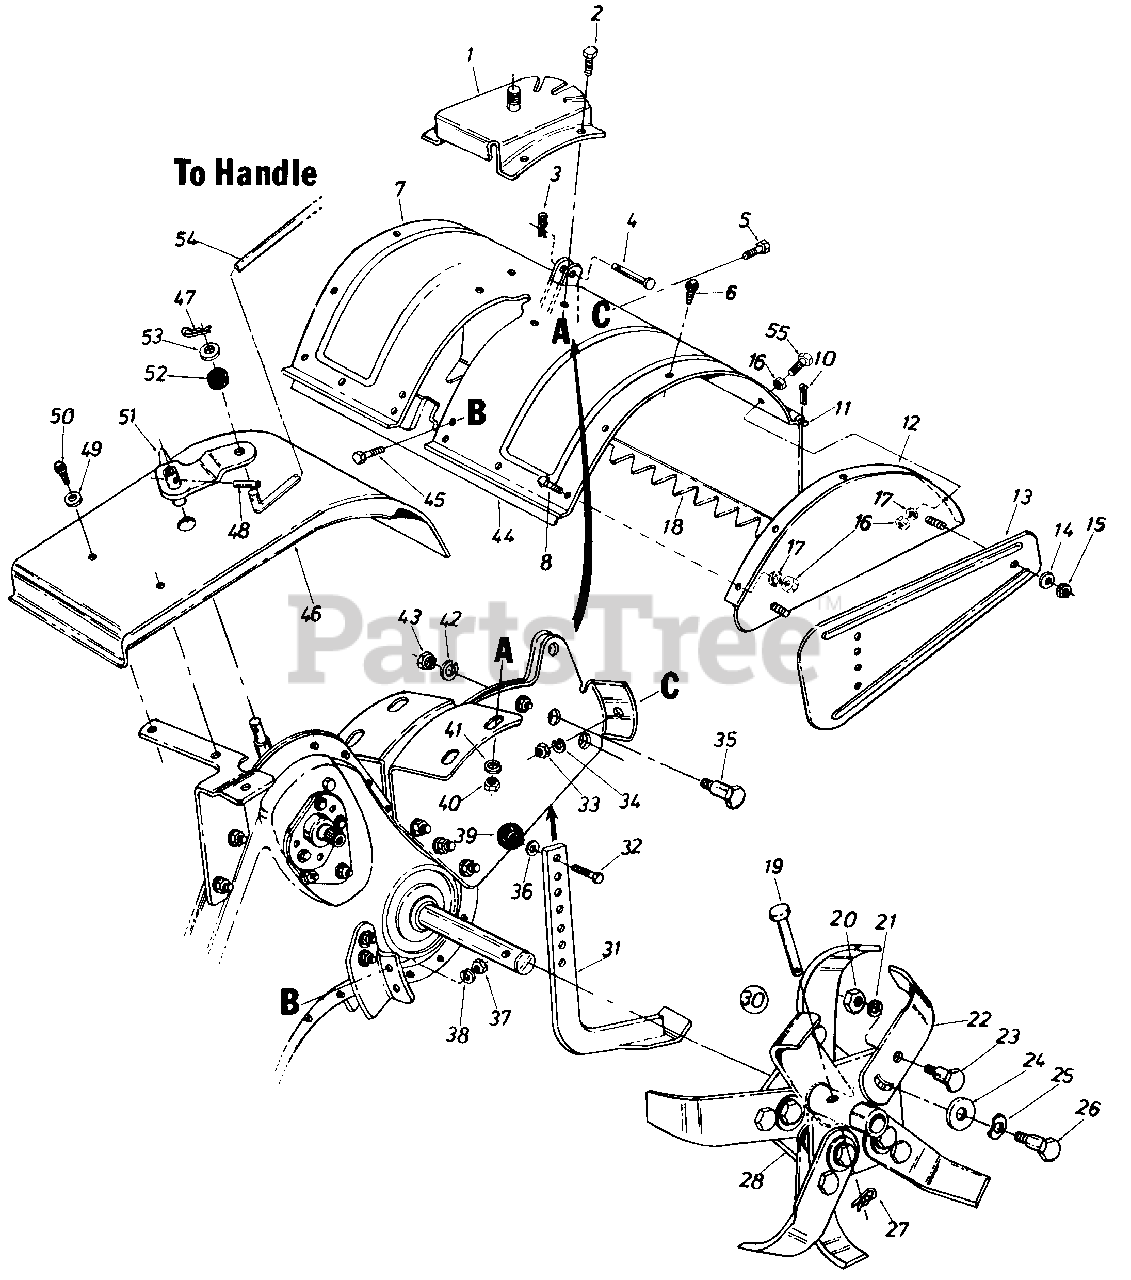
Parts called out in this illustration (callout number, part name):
3	Intern. Cotter Pin 5/16" Dia.
4	Clevis Pin .375" Dia.
5	Hex Bolt 5/16-18 x .75" Lg.
6	Hex Wash. Tap Scr.
8	Bracket Reinforcement-18"
10	Cotter Pin 3132" Dia. x .75"*
11	Tiller Flap Rod
12	End Cover Ass'y.
15	Hex Nut 5/16-18 Thd.*
16	Hex Nut 5/16-18 Thd.
17	L-Wash. 5/16" I.D.*
19	Clevis Pin .375" Dia.
20	Hex Nut 3/8-24 Thd.*
21	L-Wash. 3/8" I.D.-H.D.
22	13" Dia. Articulating Tine
23	Shld. Bolt 1/2" Dia. x .175
24	Fl-Wash. .51" I.D. x 1.50"
25	Bell-Wash. .515" I.D. x 1.14"
26	Shld. Bolt 1/2" Dia. x .320
27	Intern. Cotter Pin
28	Tine AdaDter Ass'y. 18"
30	Tine Ass'y. Comp. 18"
31	Depth Bar Ass'y.
32	Hex Bolt 3/8-16 x .75" Lg.
33	Hex Nut 5/16-18 Thd.
34	L-Wash. 5/16" I.D.*
35	Shld. Bolt 1/2" I.D. x .62" Lg.
36	Fl-Wash. 3/8" I.D. x 5/8" O.D.
37	Hex Nut 5/16-18 Thd.
38	L-Wash. 5/16" I.D.
39	Ball Knob
40	Hex Nut 3/8-16 Thd.
41	L-Wash. 3/8" I.D.
42	L-Wash. 3/8" I.D.
43	Hex Nut 3/8-16 Thd.
45	Hex Bolt 5/16-18 x .75" Lg.
46	Shift Cover
47	Intern. Cotter Pin 5/16" Dia.
48	Spring Roll Pin 3/16" Dia. x 1.00" Lg.
49	Fl-Wash. .281" I.D. x .62"
50	Hex Wash. Self-Tap Scr. l/4-20 x .50" Lg.
51	Shifting Crank Ass'y. D 0 x 2.05
52	Rubber Washer
53	Fl-Wash. .400" I.D. x 1.250"
54	Control Rod 37" Lg.
55	Hex Bolt 5/16-18 x 1 1/4" Lg.
